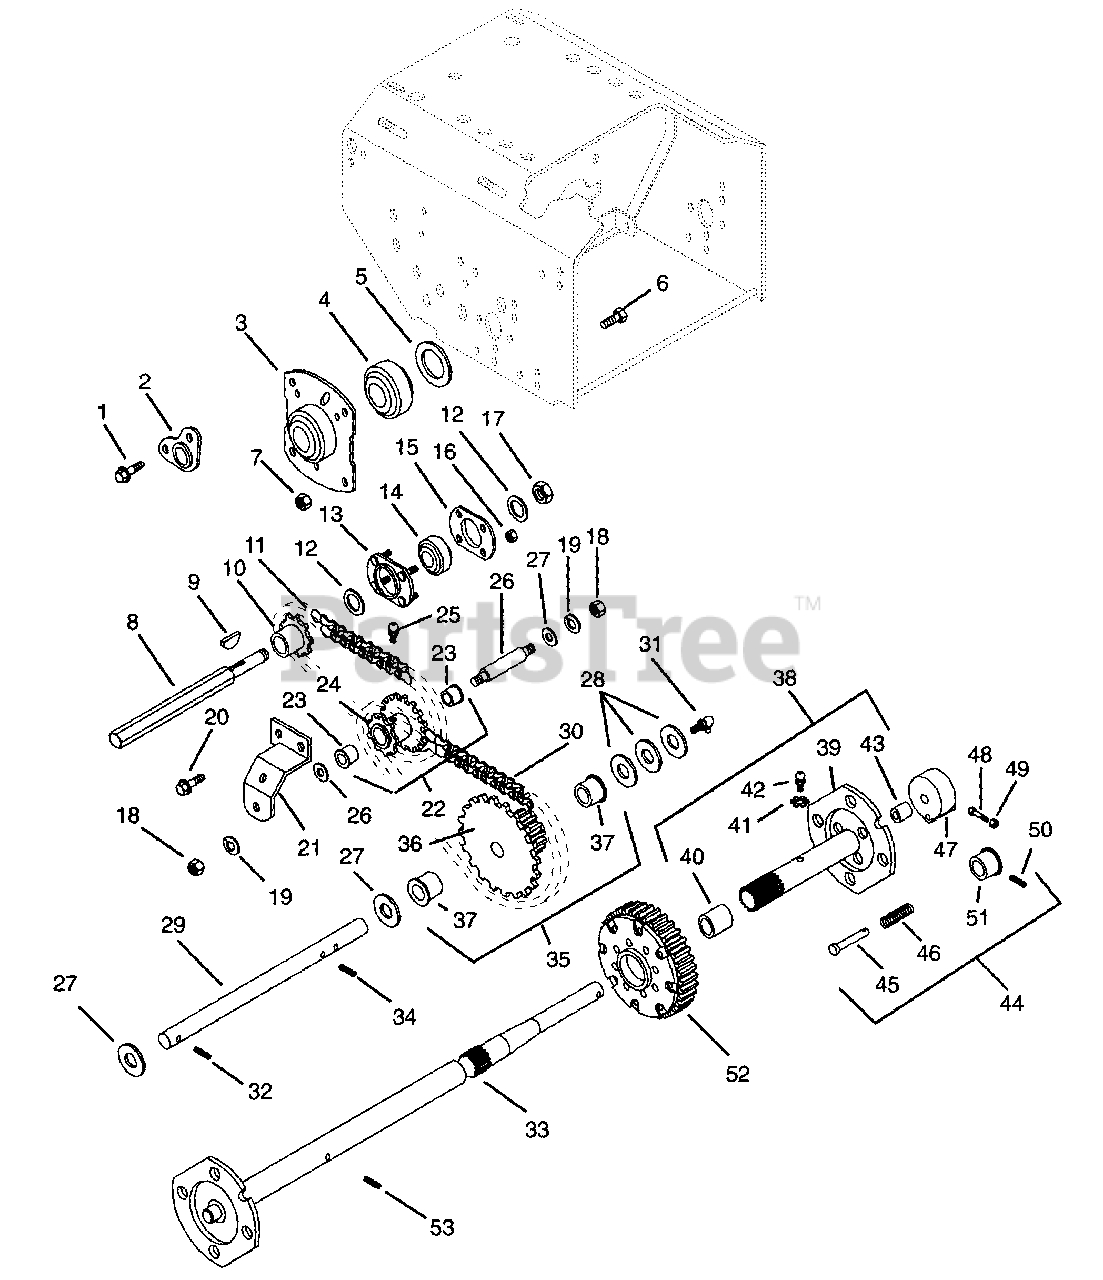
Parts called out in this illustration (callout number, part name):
1	@SCR-TAP .25-20X.50 HWH TR YWZ
2	SUPPORT, SHAFT
3	BEARING RETAINER
4	BRG-BALL 1.13X2.19X.63
5	WSHR-FL-STL 1.140X1.718X.134YZ
6	BLT-SERNK SL .25-20X.50 YWZC
7	@NUT-LK-CTR .25-20 YWZC
8	HEX SHAFT
9	KEY-WDRF .125X.625X.250 SAE5
10	9 TOOTH SPROCKET
11	ROLLER CHAIN #41 22 PITCHES
12	WSHR-FL-STL .505X.880X.072 YWZ
13	BEARING FLANGE
14	BRG-BALL .500X1.375X.437
15	BEARING FLANGE
16	NUT-LK-DUAL FACE 10-24 YWZC
17	NUT-LK-CTR .50-20 YWZC
18	@NUT-HEX .38-16 YWZC
19	WSHR-LK .375X.130 YWZC
20	@SCR-TAP .25-20X.50 HWH TR YWZ
21	SUPPORT, SHAFT
22	SPROCKET ASSEMBLY
23	BSHG-SLV .500X.625X.500 BR
24	REDUCTION SPROCKET
25	FTG-LUBE .25-28X.256 YWZC
26	REDUCTION SHAFT
27	WSHR-FL-STL .382X.812X.062
28	WSHR-FL-STL .630X1.005X.062 PL
29	PINION SHAFT
30	ROLLER CHAIN #41 38 PITCHES
31	HYDRAULIC DRIVE FITTING
32	PIN-ROLL .156X1.00
33	R H AXLE
34	PIN-ROLL .125X1.00
35	PINION & SPROCKET ASSEMBLY
36	PINION & SPROCKET
37	BSHG-FLG .625X.750X.500X.875BR
38	L.H. AXLE ASSEMBLY
39	L H AXLE
40	BSHG-SLV .750X.814X .750 BRZ
41	WSHR-LK .625X.156 MED PL
42	FTG-LUBE .25-28X.256 YWZC
43	BSHG-SLV .562X.625X.625 BRZ
44	LOCKOUT HUB ASSEMBLY
46	SG-COMP .028X.34X1.062 WLD75
47	LOCKOUT HUB
48	BLT-HEX .25-20X2.0 PL GR8 YWZC
49	@NUT-LK-CTR .25-20 YWZC
50	PIN-ROLL .093X1.00
52	DIFFERENTIAL ASSEMBLY
53	PIN-ROLL .188X1.50
